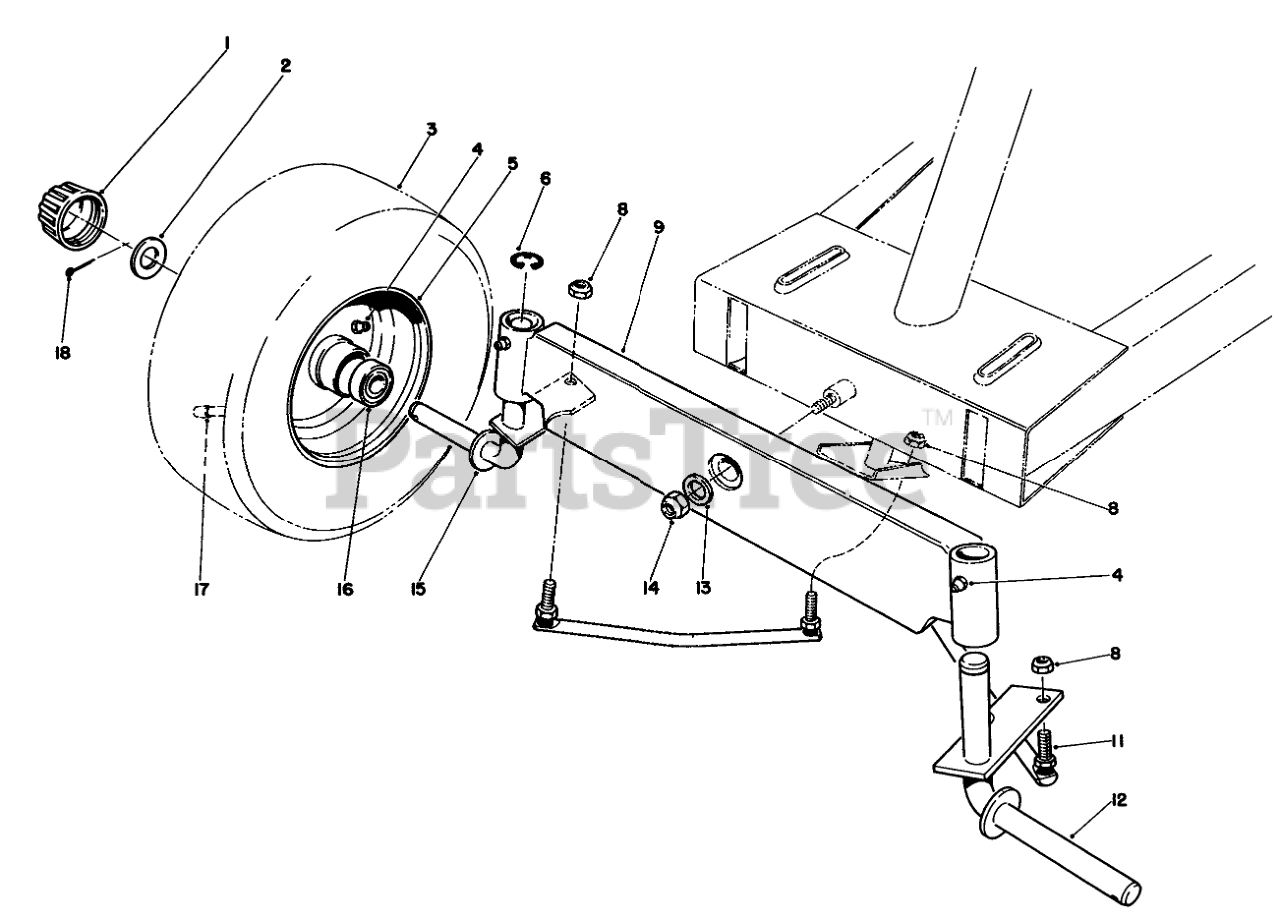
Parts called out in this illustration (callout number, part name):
1	CAP-HUB
2	WASHER-PLAIN
3	TIRE,PNEU.11X4.00X5
4	FITTING-GREASE
6	E-RING
8	NUT-LOCK
9	Axle-Front
11	TIE ROD ASM
12	Spindle-L.H.
13	WASHER-FLAT
14	NUT-LOCK, NI
15	Spindle-R.H.
16	Bearing
17	STEM-VALVE
18	PIN-COTTER
